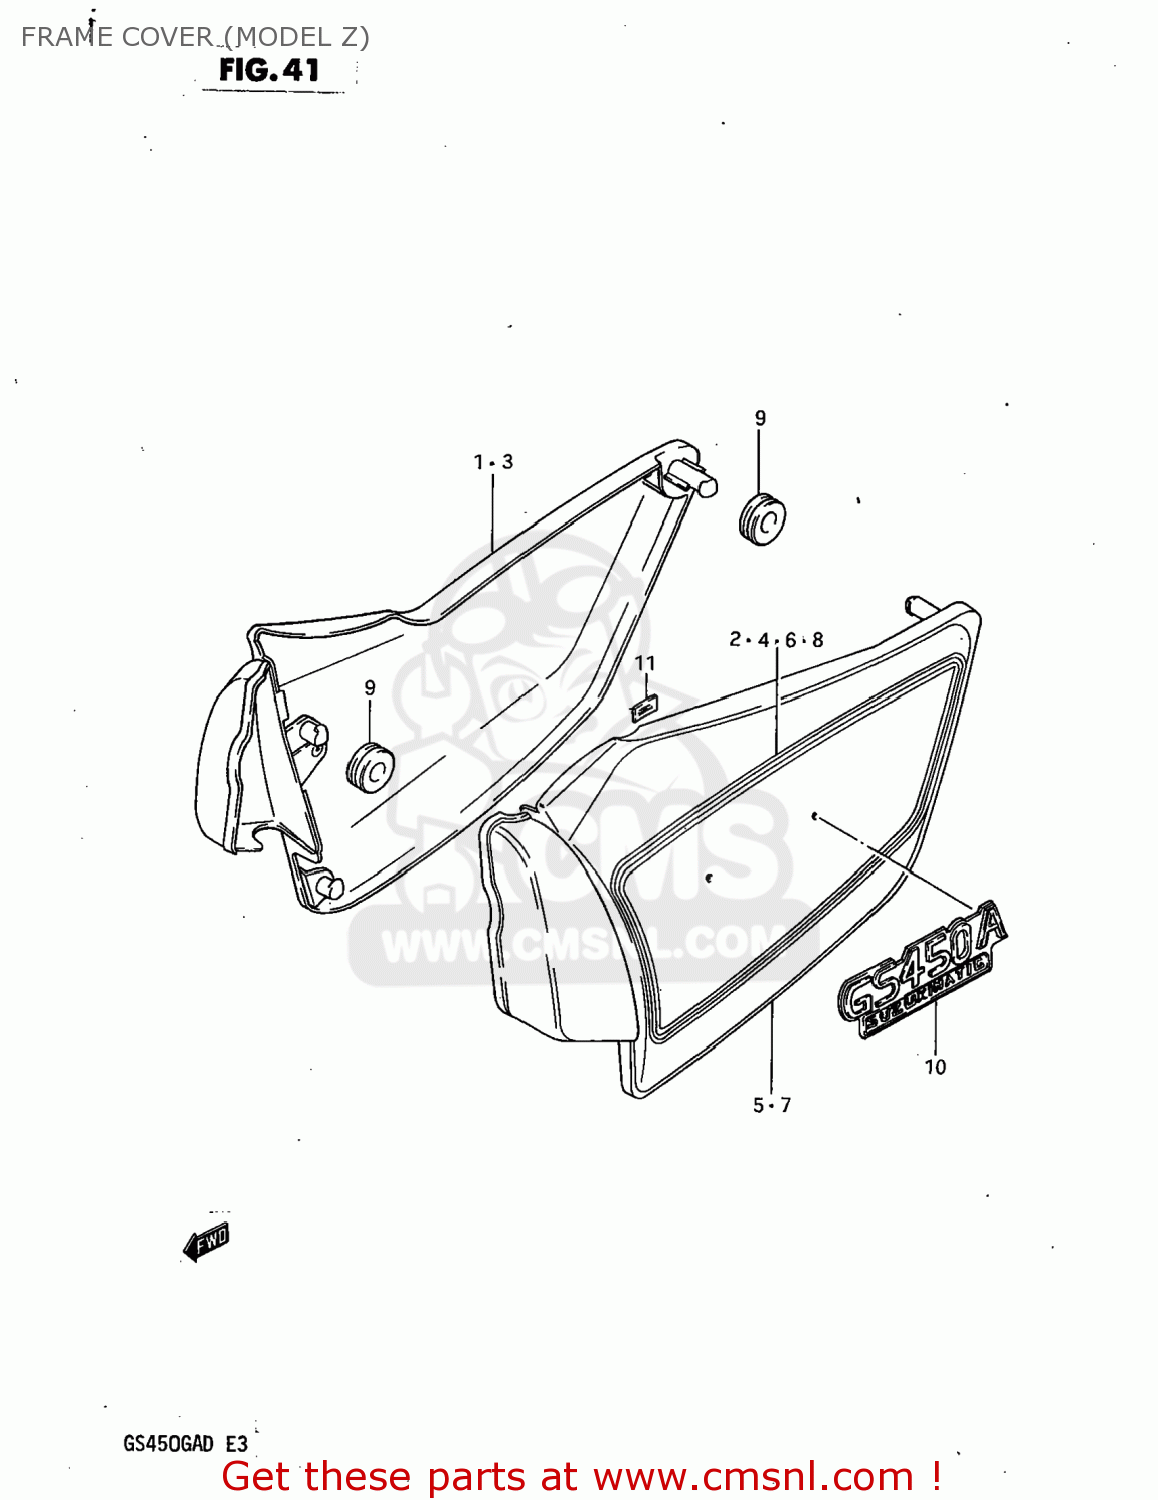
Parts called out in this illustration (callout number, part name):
1	COVER,FRAME,RIGHT
2	TAPE SET,FRAME COVER
3	COVER,FRAME,RIGHT
4	TAPE SET,FRAME COVER
5	COVER,FRAME,LEFT
6	TAPE SET,FRAME COVER
7	COVER,FRAME,LEFT
8	TAPE SET,FRAME COVER
9	CUSHION
10	EMBLEM,FRAME COVER
11	NUT
